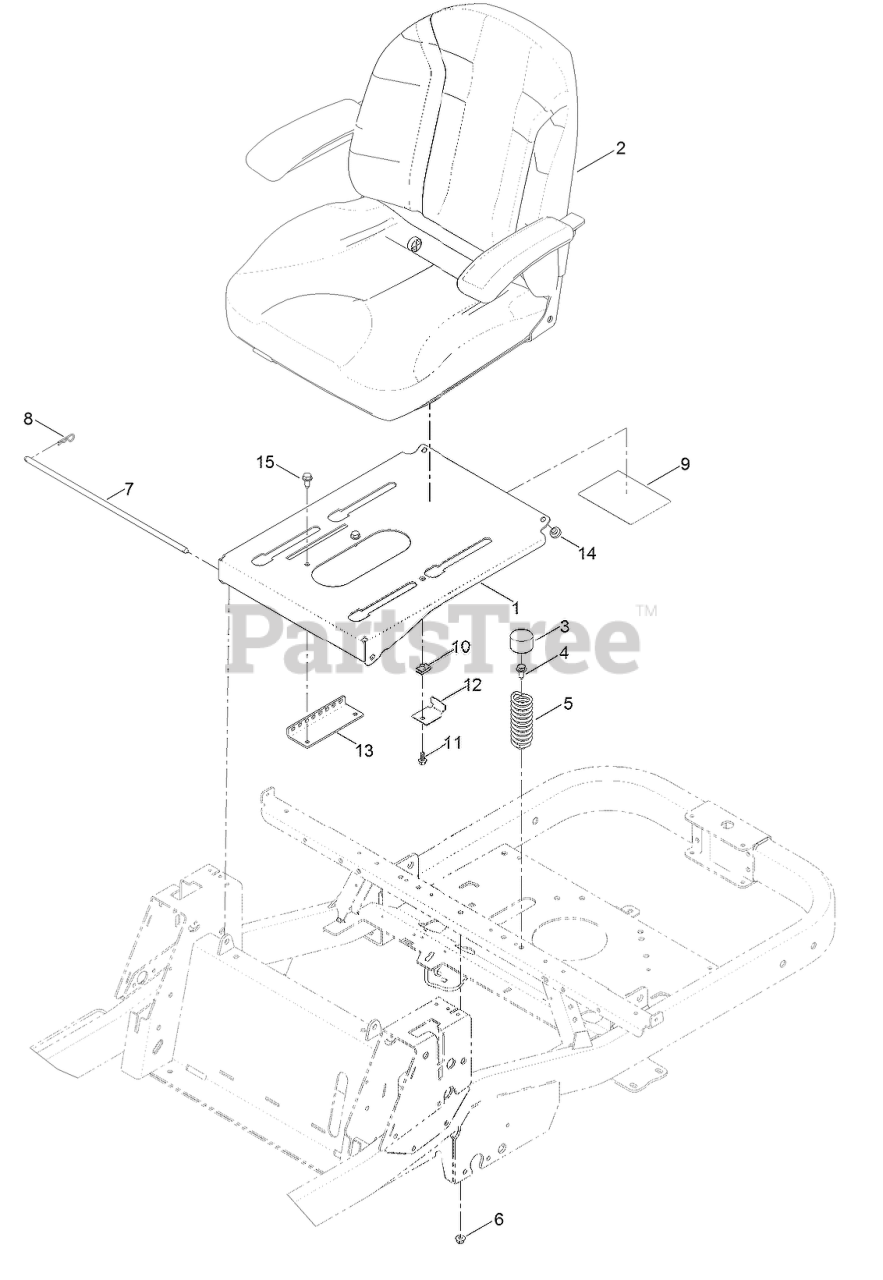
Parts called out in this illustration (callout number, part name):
1	PAN-SEAT
2	SEAT ASM
3	CAP-PROTECTOR
4	SCREW-HHF
5	SPRING-COMPRESSION
6	NUT-HF, NI
7	ROD-STOP
8	PIN-COTTER
9	DECAL-MAINTENANCE
11	SCREW-HHF
12	BRACKET-STOP, SEAT
13	BRACKET-LATCH, SEAT
14	BUMPER
15	SCREW-HWHTF
